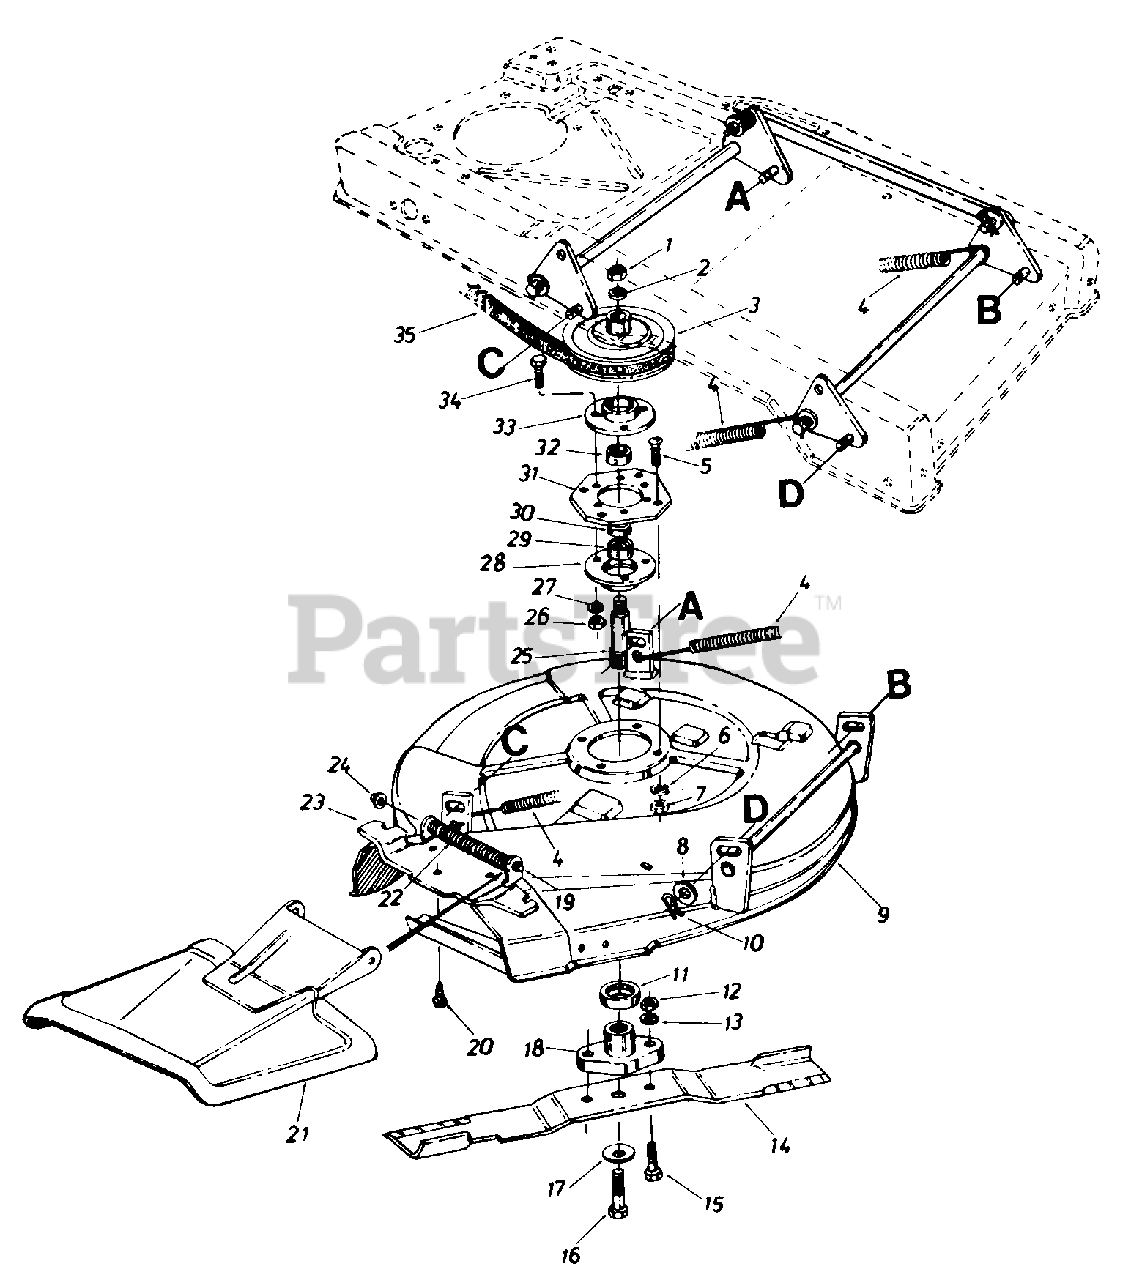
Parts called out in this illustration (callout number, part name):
1	NUT-HEX JAM 5/8-18
2	WASHER-BELL
4	SPRING-EXTENSION
5	SCREW-HEX 5/16-18 X .75
6	WASHER-LOCK-5/16
7	NUT-HEX 5/16-18
8	WASHER-FL .510 X .995 X .060
9	DECK ASSEMBLY-26IN
10	PIN-INTERN COT-1/2 DIA
11	SHIELD-BRG
12	NUT-5/16-24
13	WASHER-LOCK-5/16
14	BLADE-26IN
15	SCREW-HEX SPECIAL 5/16-24X1.0
16	BOLT-3/8 NF X 1" GR5
17	WASHER-BELL .390 ID X 1.375 X .062
18	ADAPTER-BLADE
19	PIN-HINGE
20	SCREW-HEX WASH SF TAPP
21	COVER-CHUTE-COMP
22	SPRING-TORSION
23	ADAPTER
25	SPINDLE-BLADE
26	NUT-HEX 5/16-18
27	WASHER-LOCK-5/16
28	HOUSING-BRG
29	BEARING-BALL
31	PLATE-SPINDLE MTG
32	BEARING-BALL
33	HOUSING-BRG
34	SCREW-HEX 5/16-18 X .75
35	BELT-V 1/2 X 62
